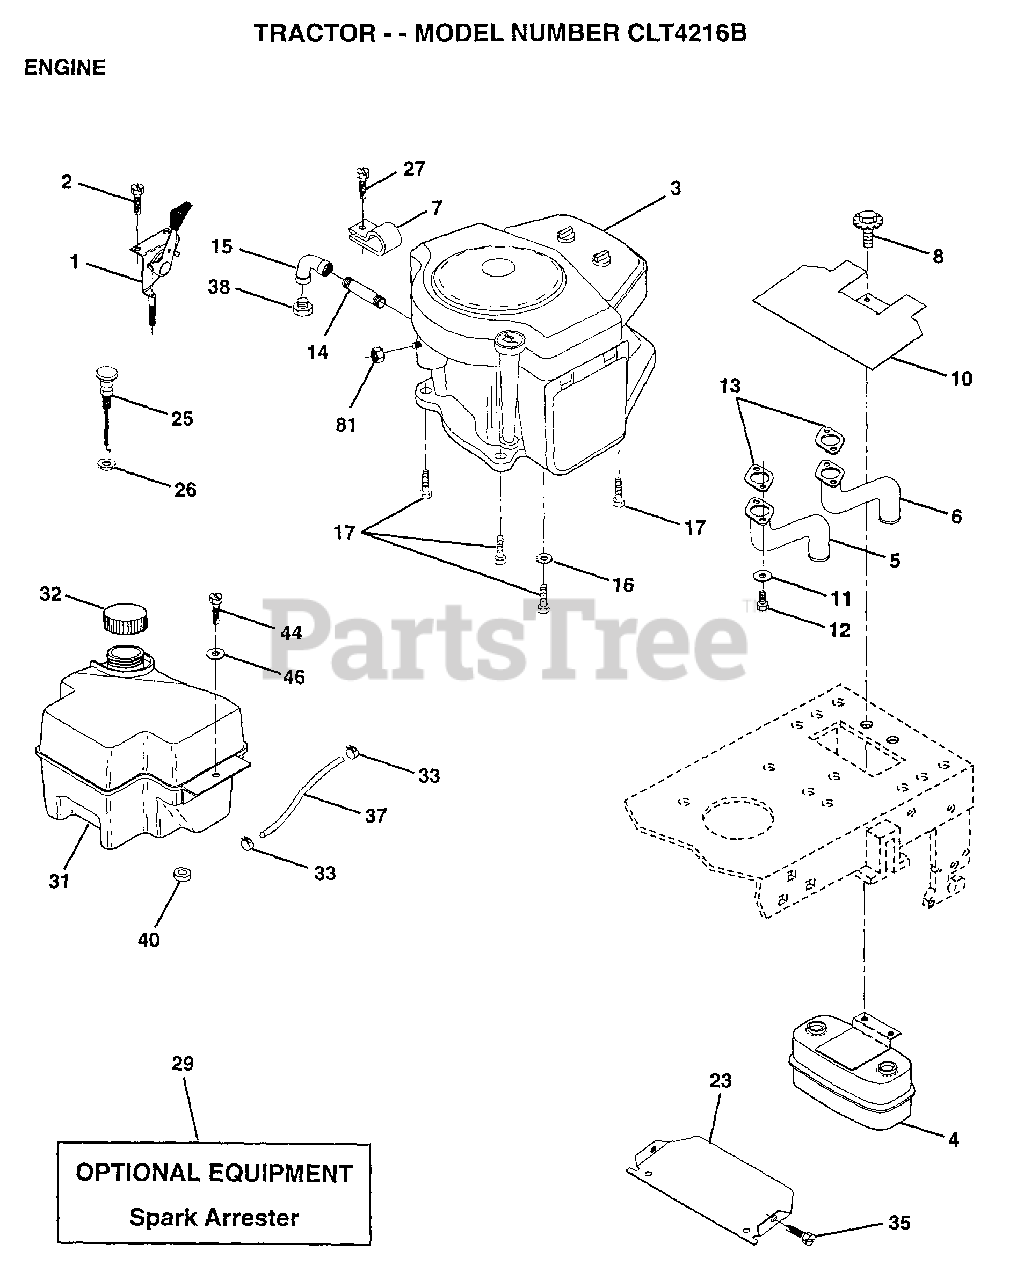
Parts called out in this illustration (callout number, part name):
1	CONTROL THRT 35.5
2	SCREW LT
4	MUFFLER.TW.LOTONE
5	EXHAUST.B&S.18.LH
6	EXHAUST.B&S.18.RH
7	CLAMP.TUBE.DBL.EN
8	BOLT.5/16-18.UNC
10	SHIELD.HEAT.
13	GASKET MUFFLER
14	PIPE NIPPLE LT
15	ELBOW
16	LOCKWASHER
17	SCREW LT
25	CONTROL.CHOKE.37
26	"NUT,KEPS 3/8-24IM"
27	"SCREW-TT,10-32 FL"
32	CAP ASM FUEL
33	HOSE CLAMP
35	SCREW
37	LINE FUEL
44	SCREW HEX CRT
46	WASHER
81	NUT
